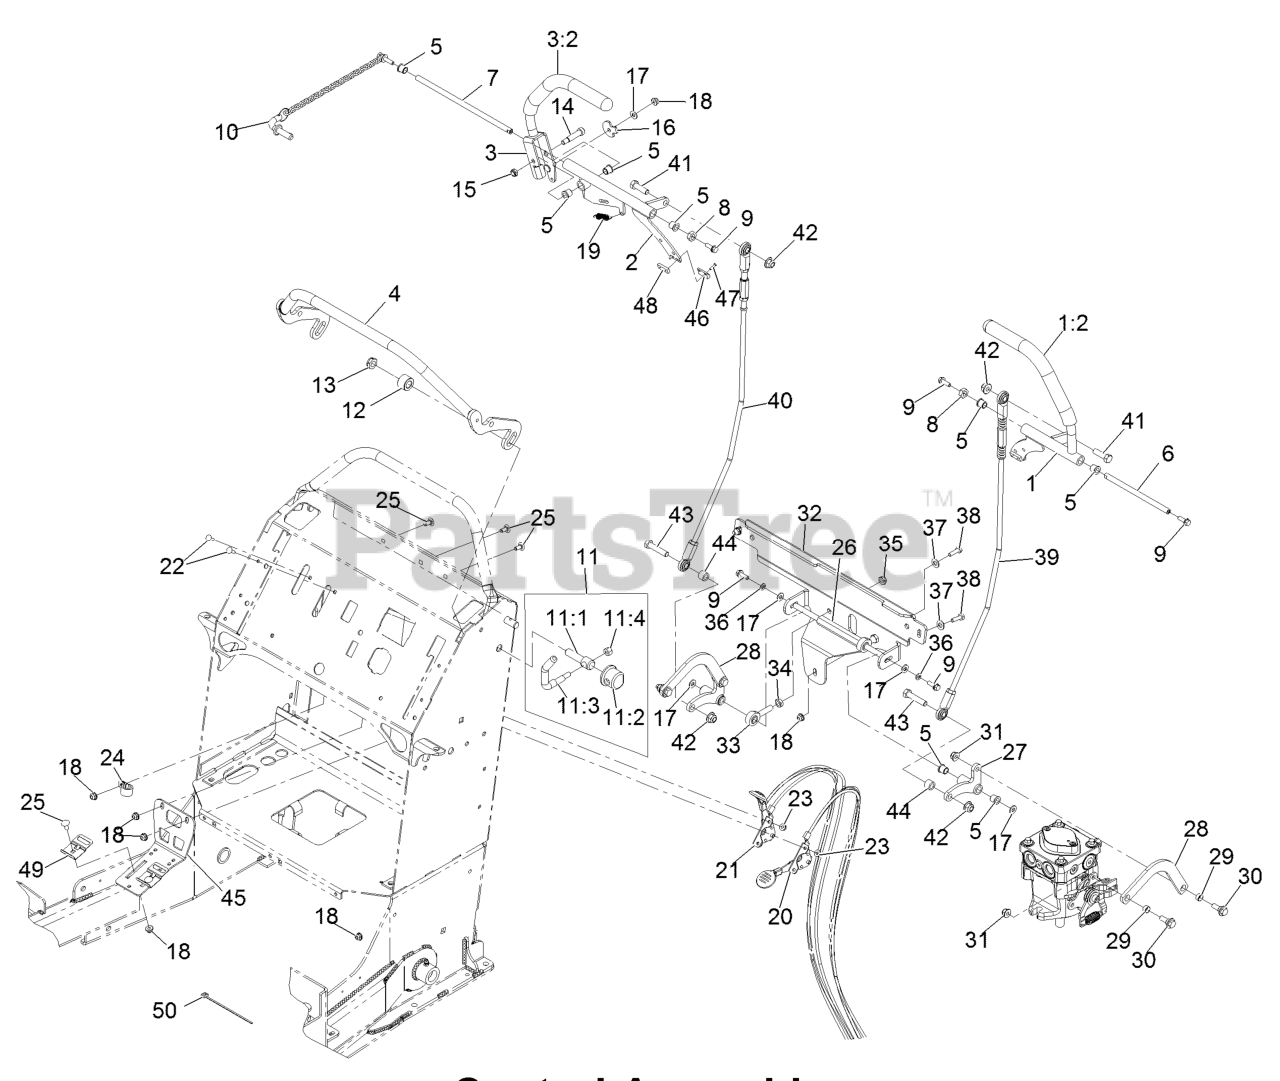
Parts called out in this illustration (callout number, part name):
1	LEVER ASM, LH
1:2	GRIP-HANDLE, CONTROL
2	MOTION CONTROL ASM-RH
3	LEVER ASM, RH
3:2	GRIP-HANDLE, CONTROL
4	TUBE ASM, FRONT SPEED CONTROL
5	BEARING
6	SHAFT-PIVOT, MOTION CONTROL
7	SHAFT-PIVOT, MOTION CONTROL
8	SPACER-SHAFT, DRIVE LEVER
9	SCREW-HHF
10	HOC PIN ASM
11	LEVER ASM
11:1	SCREW-LOCK
11:2	CAP-LOCK
11:4	NUT-LOCK, NI
12	SPACER-CLAMP
13	NUT-HEX
14	SCREW-HSH
15	NUT-LOCK, NI
16	CAM-LEVER
17	WASHER-FLAT
19	SPRING-EXTENSION
20	CONTROL-THROTTLE
21	CONTROL-CHOKE
22	BOLT-CARR
23	NUT-LOCK, FLANGE
24	CLAMP-CABLE
25	SCREW-CARR
26	SHAFT-BELLCRANK PIVOT
27	BELLCRANK-CONTROL, MOTION
28	LINK-BELLCRANK, PUMP
29	BUSHING-SLEEVE
30	SCREW-SHOULDER
31	NUT-HF, NI
32	BRACKET-BELLCRANK
33	BALLJOINT
34	NUT-HJ
35	NUT-HEX
36	SCREW-HH
37	WASHER-PLAIN
38	SCREW-HH
39	LINKAGE-TRACKING CONTROL,LH
40	LINKAGE-TRACKING CONTROL,RH
41	SCREW-HH
42	NUT-HF, NI
43	SCREW-HH
44	SPACER-WHEEL
45	BRACKET, REED SWITCH
46	ACTUATOR-SWITCH, REED
47	SCREW-HH
48	PLATE-TAPPED
49	CLAMP, REED SWITCH
50	TIE-CABLE
